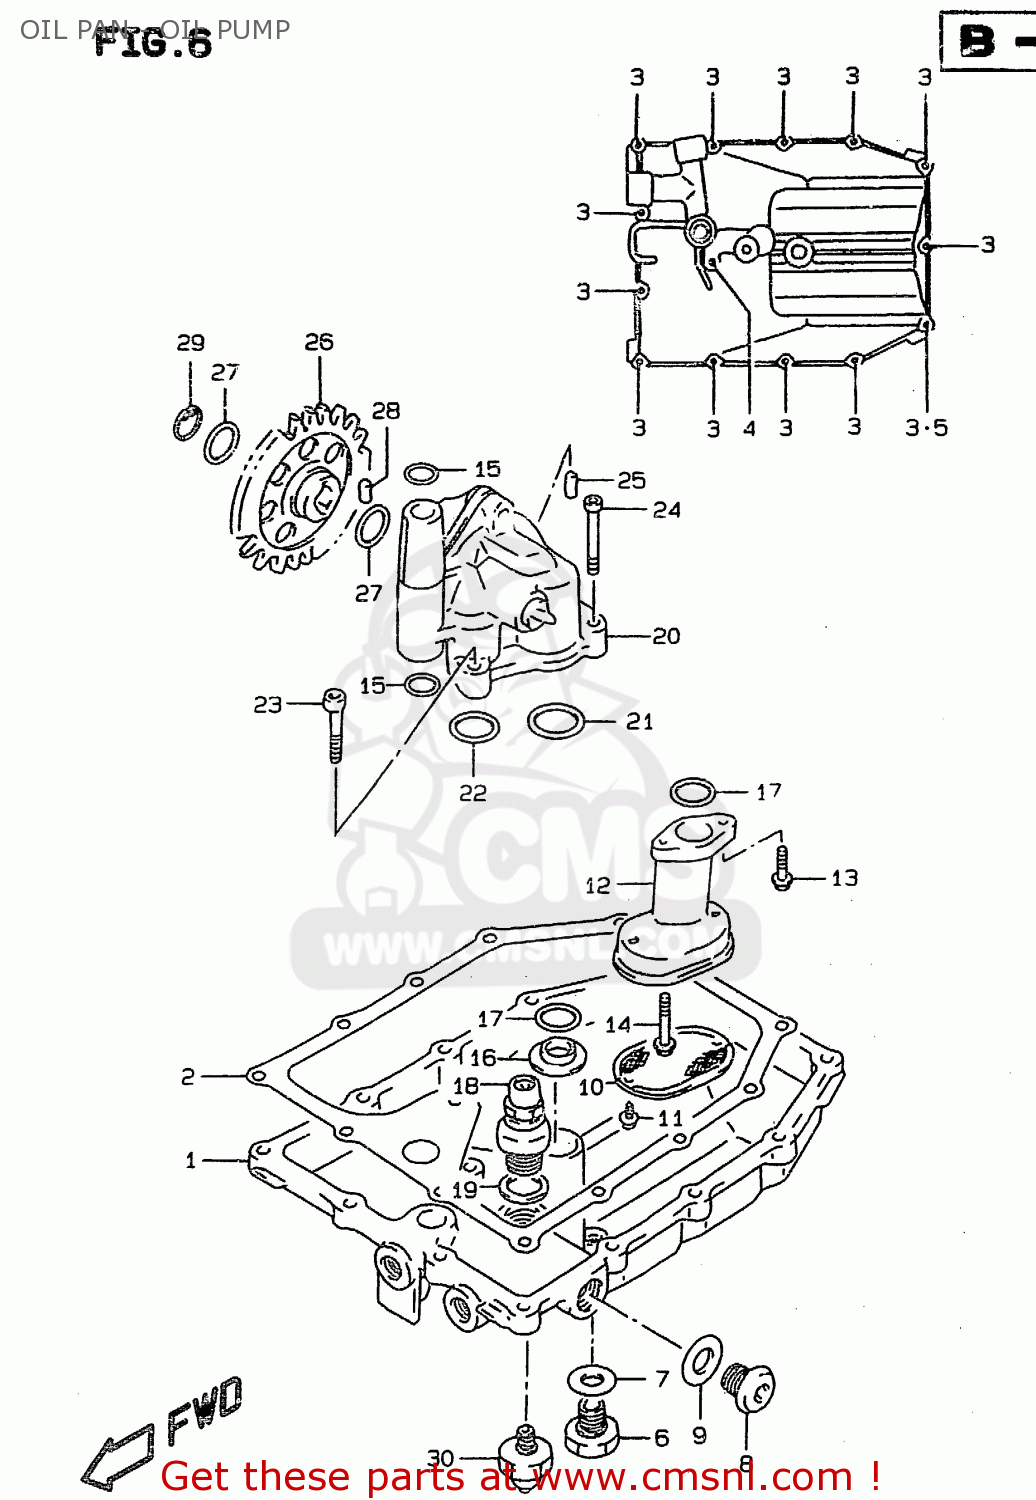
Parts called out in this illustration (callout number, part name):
1	PAN,OIL
2	GASKET,OIL PAN (NAS)
3	SCREW
4	BOLT
5	GASKET(5.8X11X1.2) (NAS)
6	PLUG
7	GASKET(13.8X18.8X4.8) (NAS)
8	PLUG
9	GASKET(16X22X2) (NAS)
10	STRAINER,ENGINE OIL
11	BOLT
12	PROTECTOR,OIL STRAINER
13	BOLT
14	BOLT, HYDRAULIC UNIT NO.2
15	O RING(D:2.4,ID:11.8)
16	GASKET,OIL OUTLET (NAS)
17	O RING(D:3.2,ID:17.8)
18	VALVE ASSEMBLY,OIL RELIEF
19	GASKET(16X22X2) (NAS)
20	PUMP ASSY,ENGINE OIL
21	O RING(D:2.4,ID:26.2)
22	O RING(D:3.2,ID:17.8)
23	BOLT
24	BOLT
25	PIN
26	GEAR,OIL PUMP DRIVEN(NT:37)
27	SHIM
28	PIN(5X18)
29	CIRCLIP,12 MM
30	SWITCH ASSEMBLY,OIL PRESSURE
